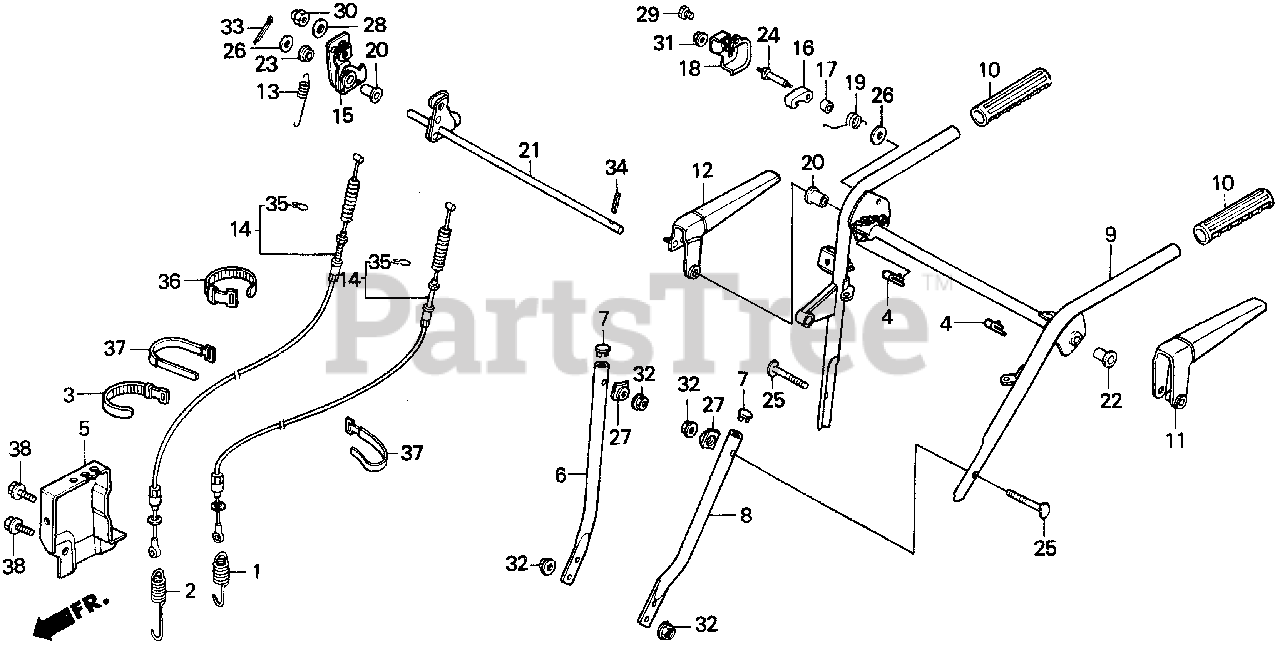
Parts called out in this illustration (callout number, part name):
1	SPRING, TENSION ROLLER
2	SPRING, TENSION ROLLER (AUGER)
3	BAND B1, CABLE
4	RUBBER, STOPPER
5	HOLDER, WIRE
6	HANDLE, R. (LOWER)
7	CAP, HANDLE (LOWER)
8	HANDLE, L. (LOWER)
9	PIPE, HANDLE (UPPER)
10	GRIP, HANDLE
11	LEVER, CLUTCH
12	LEVER, AUGER CLUTCH
13	SPRING, CLUTCH LEVER
14	CABLE, CLUTCH
15	BOSS, CAM LOCK
16	RATCHET, LEVER
17	COLLAR, RATCHET
18	COVER, RATCHET
19	SPRING, RATCHET
20	BUSH (13X23)
21	SHAFT, CLUTCH LEVER (NOT AVAILABLE)
22	BUSH (14MM)
24	BOLT, PIVOT (6MM)
25	BOLT, HANDLE HOLDER
26	WASHER (10MM)
27	WASHER, FRAME JOINT
28	WASHER (6MM)
29	BOLT, FLANGE (6X10)
30	NUT, CAP (6MM)
31	NUT, FLANGE (6MM)
32	NUT, FLANGE (8MM)
33	PIN, COTTER (3.0X18)
34	PIN, SPRING (3X16)
35	CLIP, TUBE (C9)
36	BAND B1, CABLE
37	BAND B2, CABLE HARNESS
38	BOLT, FLANGE (6X16)
